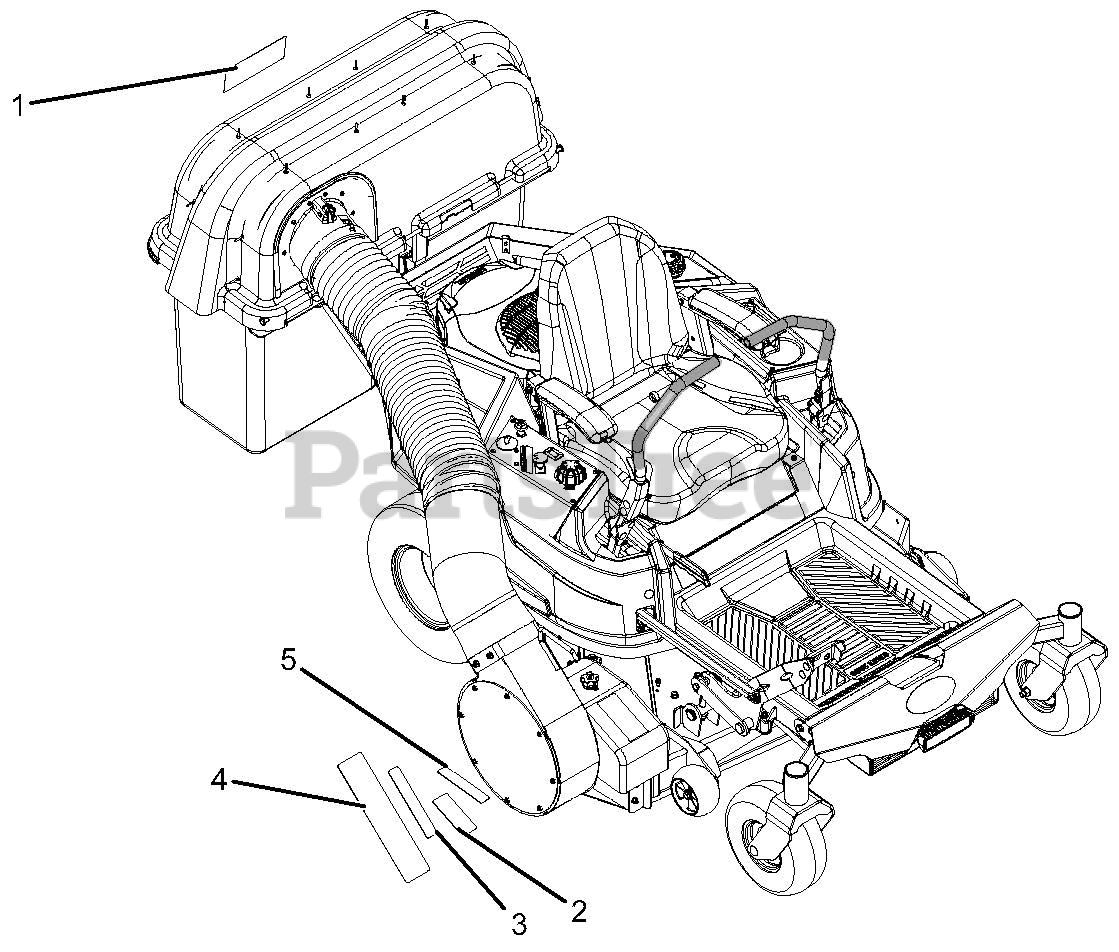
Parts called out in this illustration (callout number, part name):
1	DECAL, BAGGER COVER
2	DECAL, MOWER PAN DANGER
3	DECAL- DANGER
4	DECAL-CAUTION, GRASS PUMP
5	DECAL, WARNING
